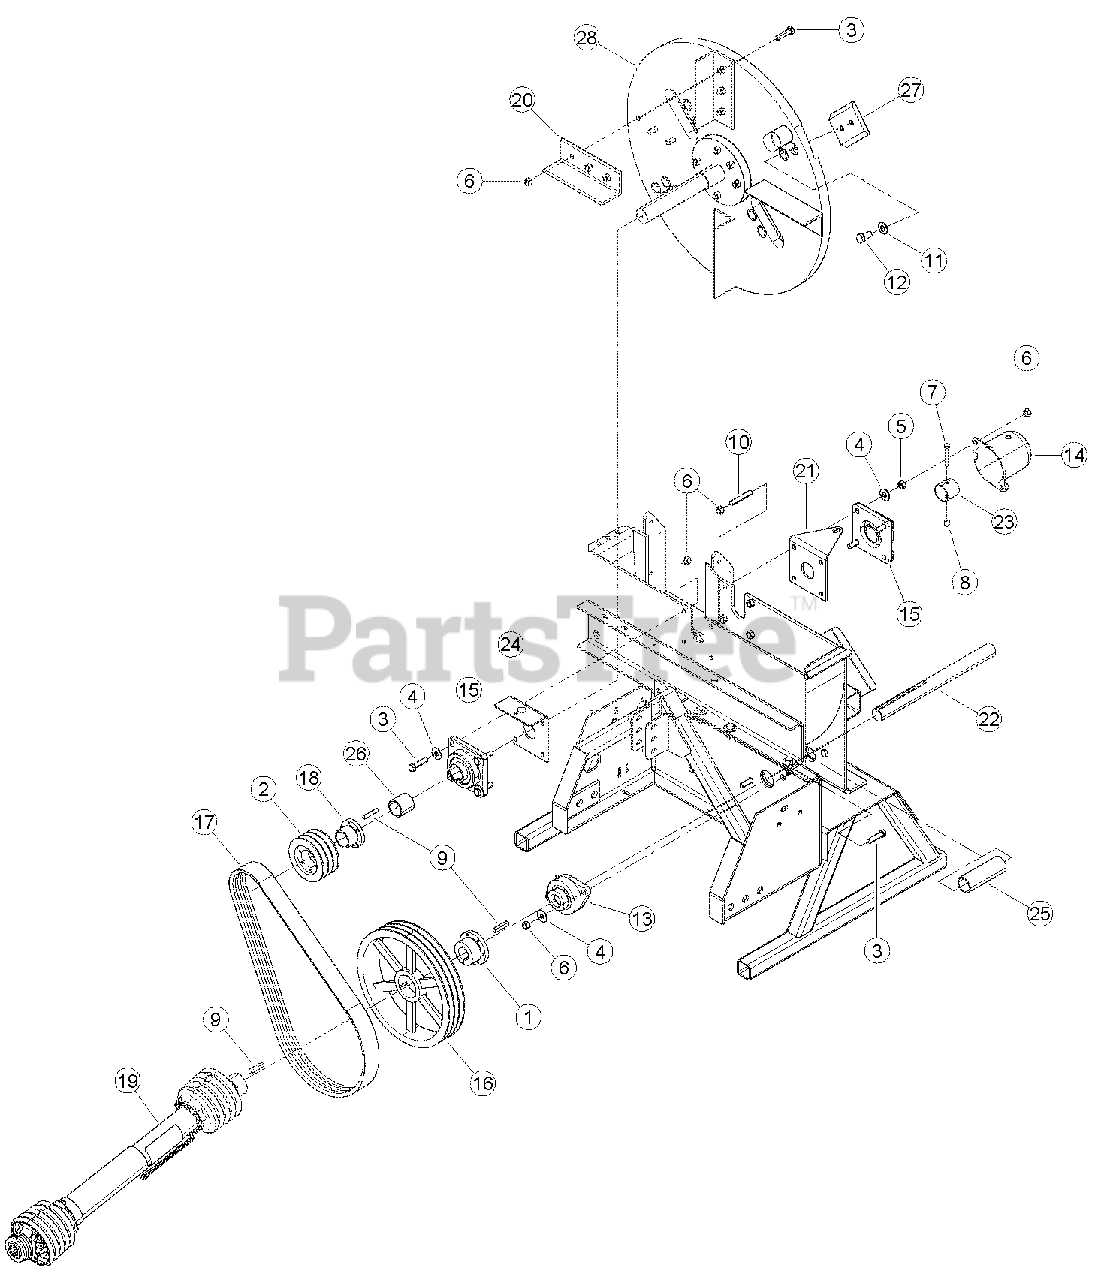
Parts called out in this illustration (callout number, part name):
1	BUSHING, SK 1-1/2"
2	SHEAVE 3B4.8 SD
3	BOLT, 1/2 X 2 HEX HD GR5 ZP
4	WASHER, 1/2 FLAT ZP
5	NUT, 1/2 HEX NC ZP
6	NUT, 1/2 CENTERLOCK GRB ZP
7	BOLT, 3/8 X 2-1/2 HEX HD GR5 ZP
8	NUT, 3/8 NE NYLOCK ZP
9	KEY, 3/8 SQUARE X 2 LONG PLAIN
10	STUD, 1/2-13 X 3 LONG B7 ZP
11	WASHER, 5/8 SAE HARDENED
12	BOLT, M16 X 2.0 X 30 HEX HD W/PATCH
13	BEARING, 2 BOLT FLANGE 1-1/2" BORE
14	CAP, LARGE SHAFT
15	BEARING, 4 BOLT FLANGE 1-3/4" BORE
16	SHEAVE, 3B13.6 SK
17	BELT, 3RB64
18	BUSHING, SD 1-3/4"
19	WAS PN 16958, DRIVESHAFT (REPLACED AND SUPERSEDED. FOR SERVICE ORDER PN 32219-00 DRIVELINE).
19	DRIVELINE
20	PADDLE, BIG CHIPPER
21	WAS 71140, BEARING BRACKET. (REPLACED AND SUPERSEDED. FOR SERVICE ORDER PN 75960-12, BRACKET, DISK LOCK. (IF ORDERING NEW BRACKET ALSO ORDER PN 14544-00-HITCH PIN, 15001-BOLT, PN 15030-WASHER & PN 15355-NUT. SEE PAGES 8 & 9 FOR DETAILS))
22	JACKSHAFT, CHIPPER DRIVE
23	COLLAR, CHIPPER LOCK
24	WELDMENT, LEFT BEARING BRACKET
25	SHIELD, SHAFT
26	SPACER, 2.0 X 1.88
27	BLADE, BIG CHIPPER
28	ASSEMBLY, 9 INCH CHIPPER DISK
